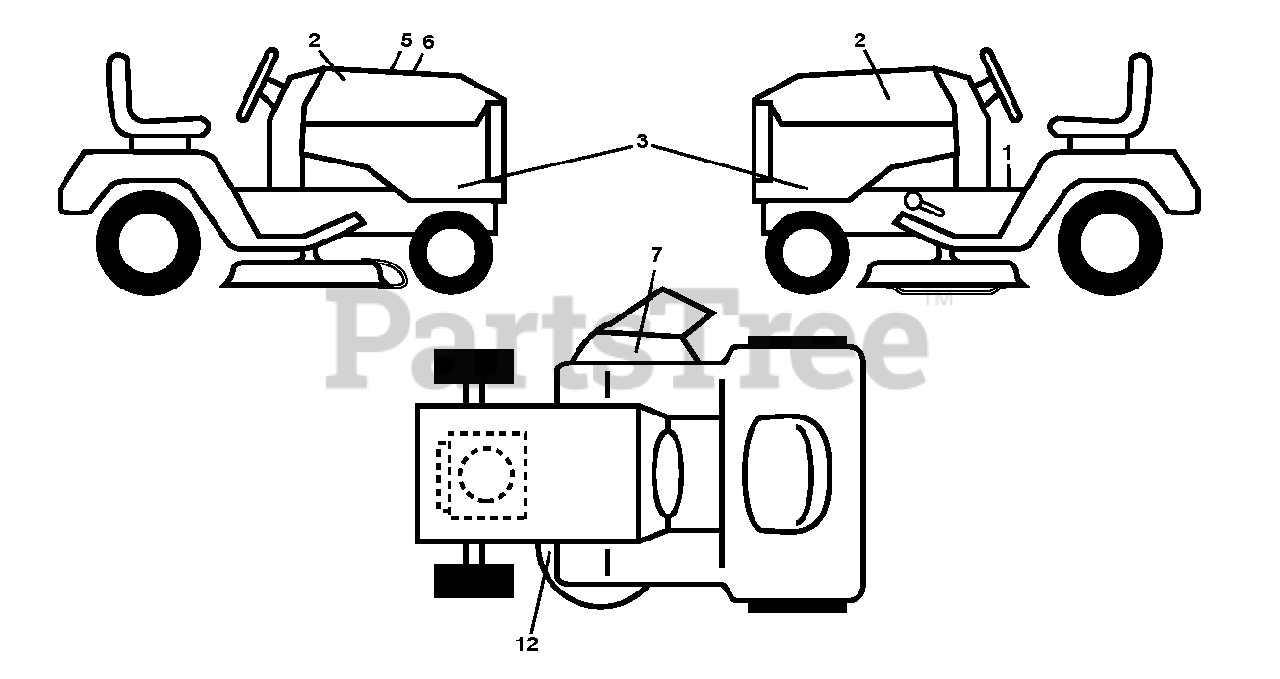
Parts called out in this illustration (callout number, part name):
1	DECAL.FENDER.WARNING.ENGLISH
2	Decal, WB 178MM 15 Husqvarna NEWBRAN
3	Decal, Side Panel YTH20K46 Set
5	DECAL.WARNING.CUST.RESP.E85.
6	Decal, Replacement Kohler KT7 TLW 46 K46AL
7	DECAL, DECK DEFLECTOR, WARNING
12	DECAL.V-BELT.SCH.42/46"MEC/ELE
